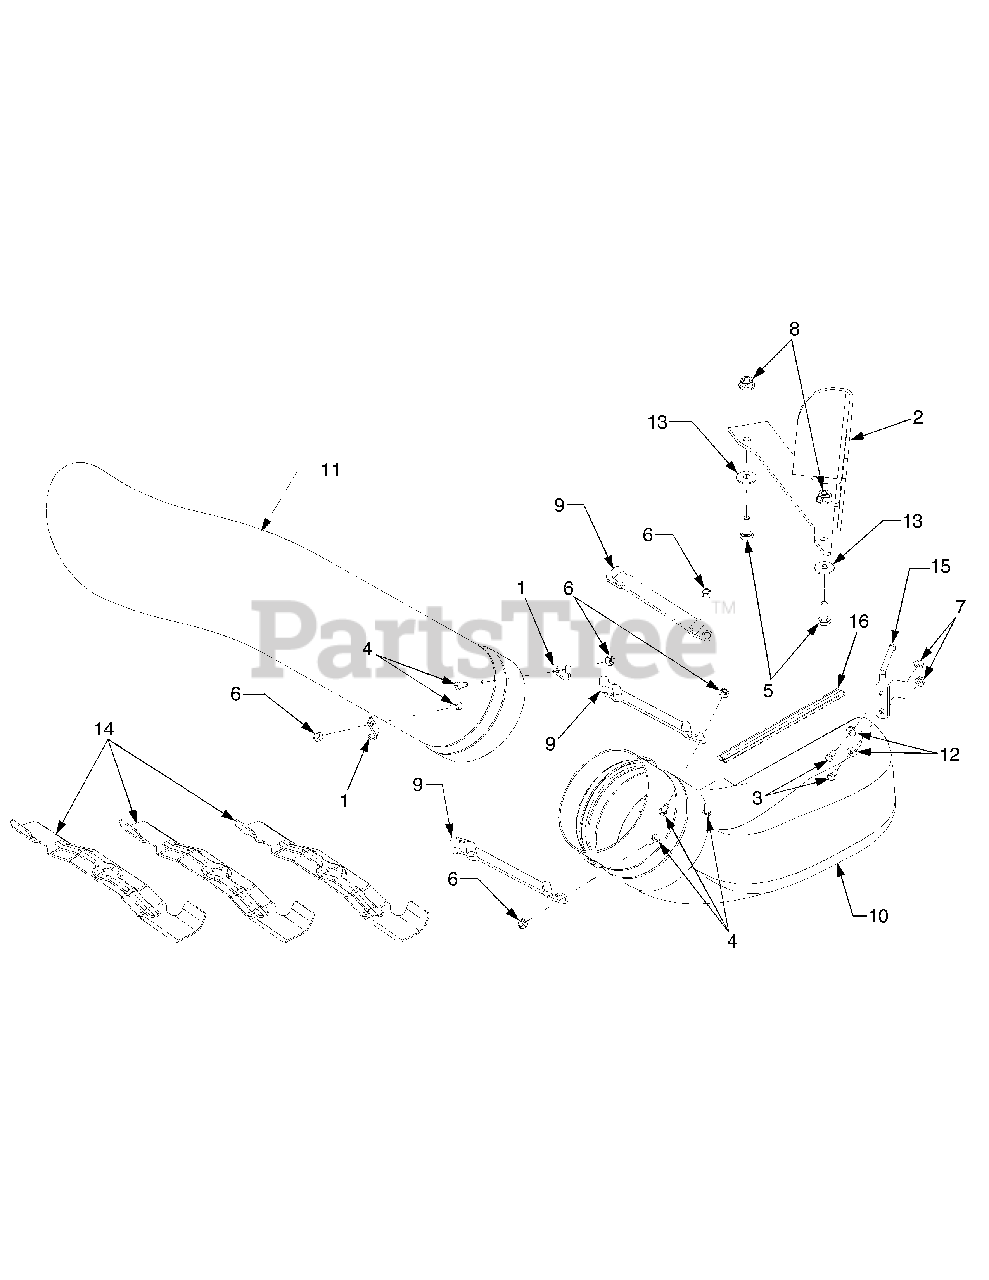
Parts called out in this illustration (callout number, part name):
1	Bracket, Retainer Hook
3	Screw, Hex Wash. Hd. Tapp 1/4-20 x 75
4	Screw, Hex Cap, 1/4-20 x .62 GR5
5	Screw, Hx Cap, 1/4-20 x .75 GR5
6	Nut, Hex Insert Lock, 1/4-20
7	Nut, Hex Flange Lock, 1/4-20
8	Nut, Hx Flange Insert Lock, 1/4-20
9	Strap Assembly, Retainer
9	Wire Hook, Eyelet
9	Wire Hook, Rectangular
10	Chute, Discharge (Includes Ref. Nos. 3, 7, 12 and 15)
11	Tube, Chute
12	Washer, Flat, .28 x .74 x .063
13	Washer, Belleville, .265 x .75 x .062
14	Blade, High Lift
15	Rod, Chute Mounting
16	Seal, Heat Baffle, 12"
